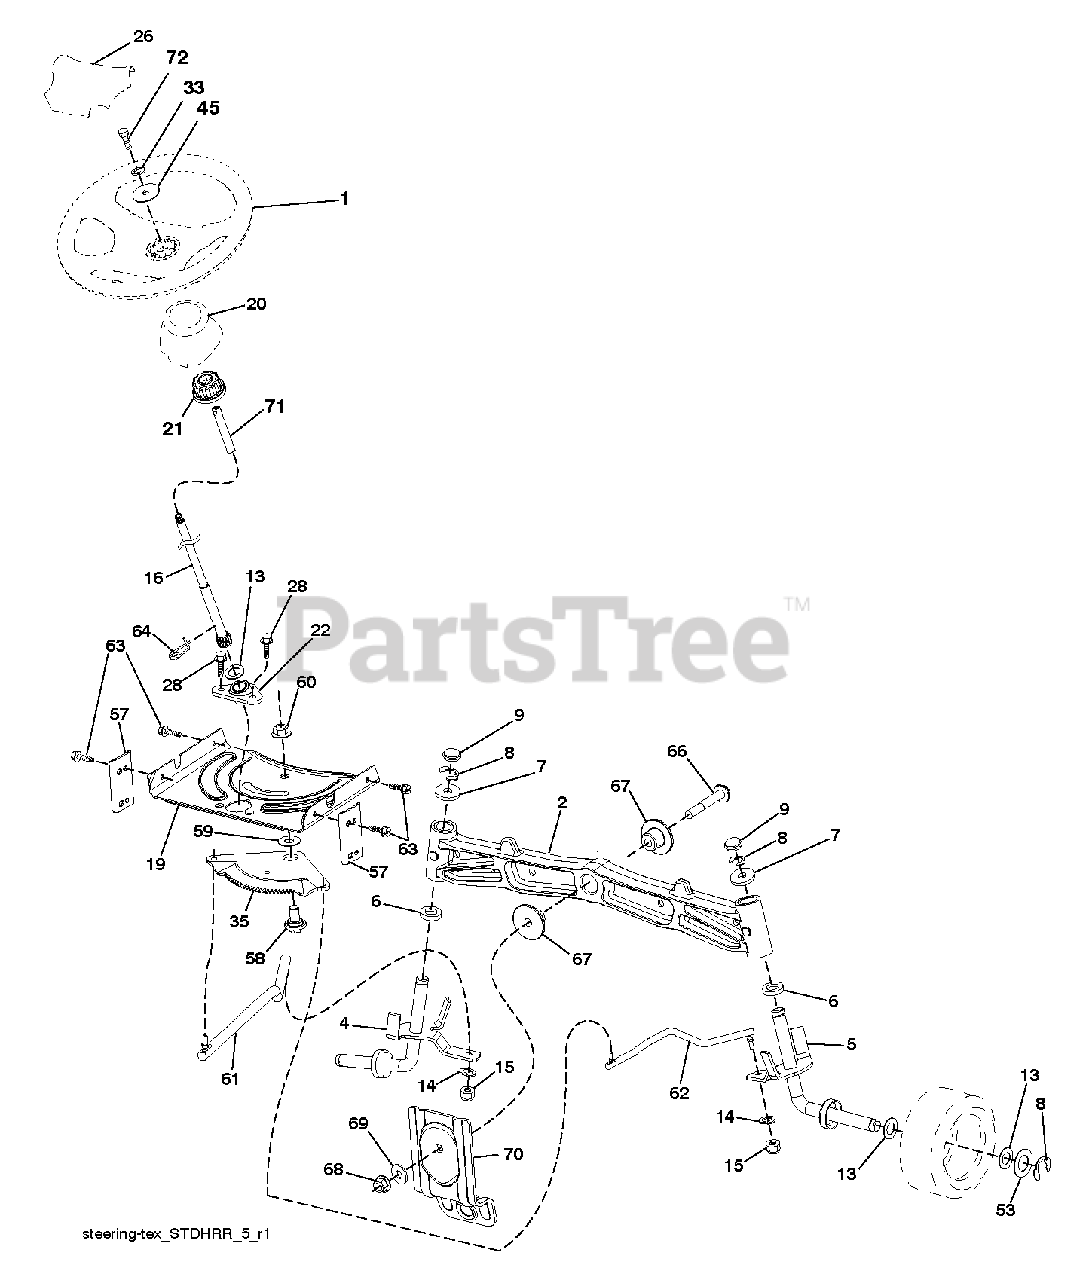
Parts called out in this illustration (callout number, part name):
1	WHEEL, STEERING
4	SPINDLE.WELDED.LH.15"T
5	SPINDLE.WELDED.RH.15"T
6	BRNG T
14	WASHER, LOCK 3/8
15	NUT CROWNLOCK 3/8-24
19	PLATE.STEER.DDL.NLT/NG
21	ADAPTER, WHEEL STNG
22	STEERING.SUPT.LOWER.
26	INSERT, WHEEL STEERING
28	SCREW, 3/8-16X3/4
35	GEAR.SECTOR.PLATE.DDL.
58	BOLT.SHOULDER.SECTOR.P
59	WASHER.THURST.SECTOR.S
60	NUT FLANGE LOCK 5/8-11
61	DRAGLINK.LH.BALLSTUD.D
62	DRAGLINK.RH.BALLSTUD.D
63	SCREW
64	RETAINER.CLIP.SPRING.S
66	BOLT HEX FGHD 7/16-14 X 3 SERR
67	BUSHING.PM.FRONT AXLE
68	NUT.LOCK.FLANGE.7/16
69	WASHER.1.5X.505X.118
70	BRKT.DECK.SUSPENSION.F
